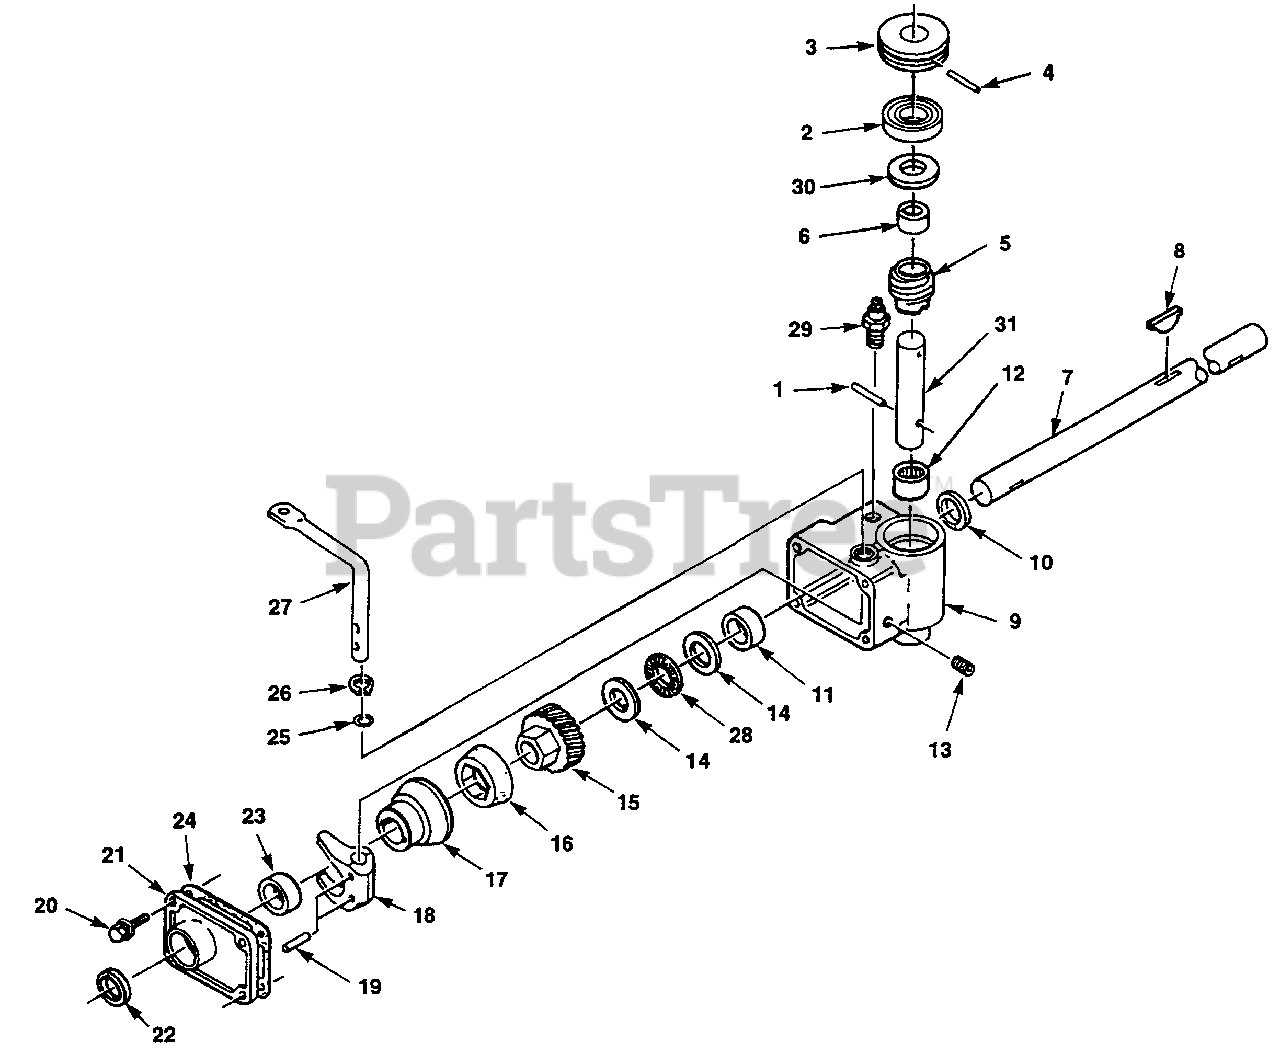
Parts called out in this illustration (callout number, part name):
2	4BALL BEARING-TBO
3	PULLEY
4	Pin - Roll 3/32 x 1 1/4"
5	WORM & SPACER
6	SPACER - Worm
7	SHAFT - Drive
9	HOUSING - Gear box
11	BUSHING TBO
12	BEARING,NEEDLE TBO
13	PLUG - Pipe
16	CONE - Friction
17	DRUM - Clutch
19	PIN - Groove
20	SCREW- 1/4-20 x 7/8
21	COVER - Gear Box
23	BUSHING TBO
24	GEARBOX GASKET
26	TRU-ARC RING
27	LEVER- Shift
28	BEARING - Needle
31	WORM - Shaft
